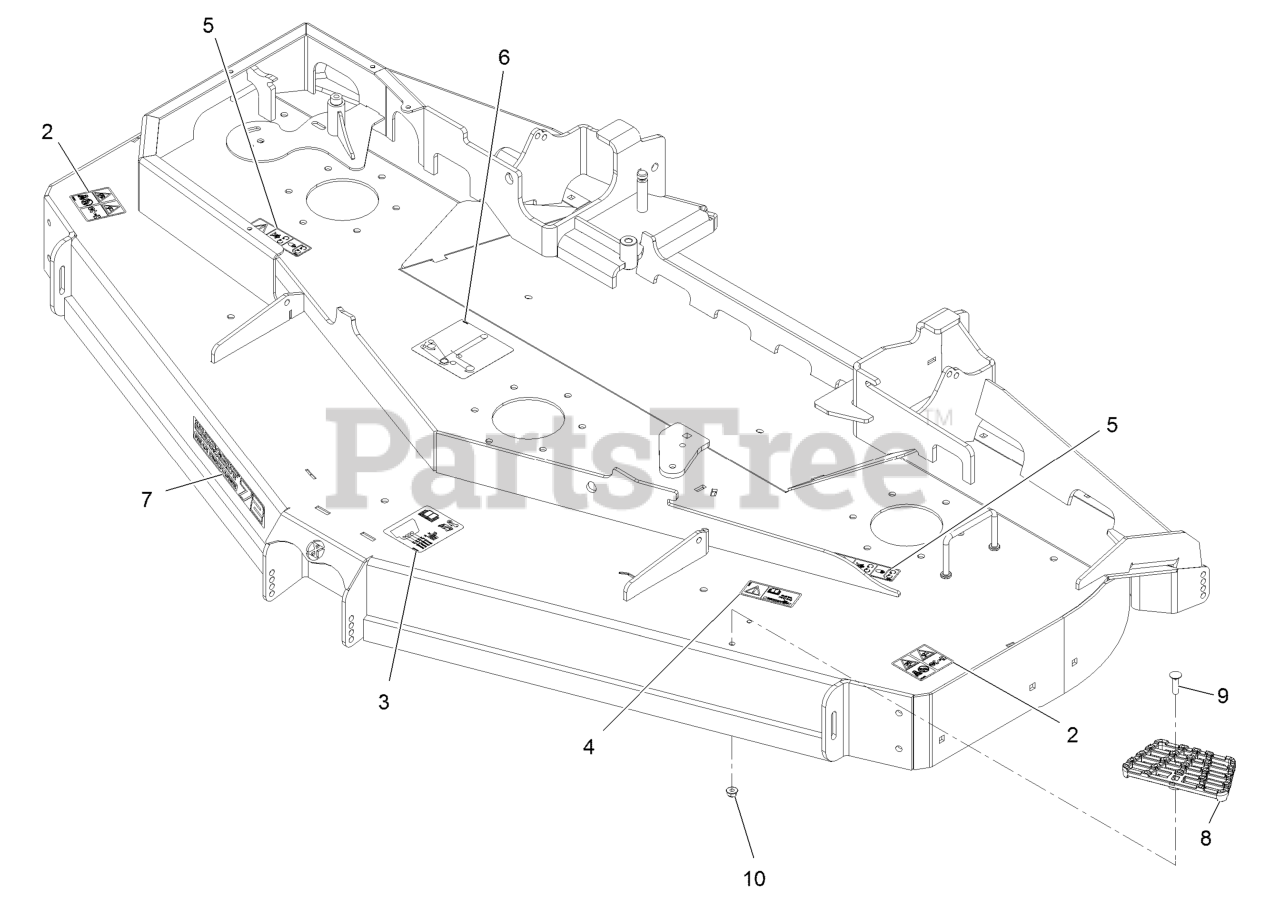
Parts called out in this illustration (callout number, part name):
2	Decal-Danger, Thrown Object
3	Decal-Roller, Anti-Scalp
4	Decal-Bolt Torque
5	Decal-Cover, Missing
6	Decal-Routing, Belt
7	Decal, 72Rd
8	Step-Deck
9	Bolt-Carriage 5/16-18 X 1 1/4
10	Nut-Nyloc 5/16-18 Flg
